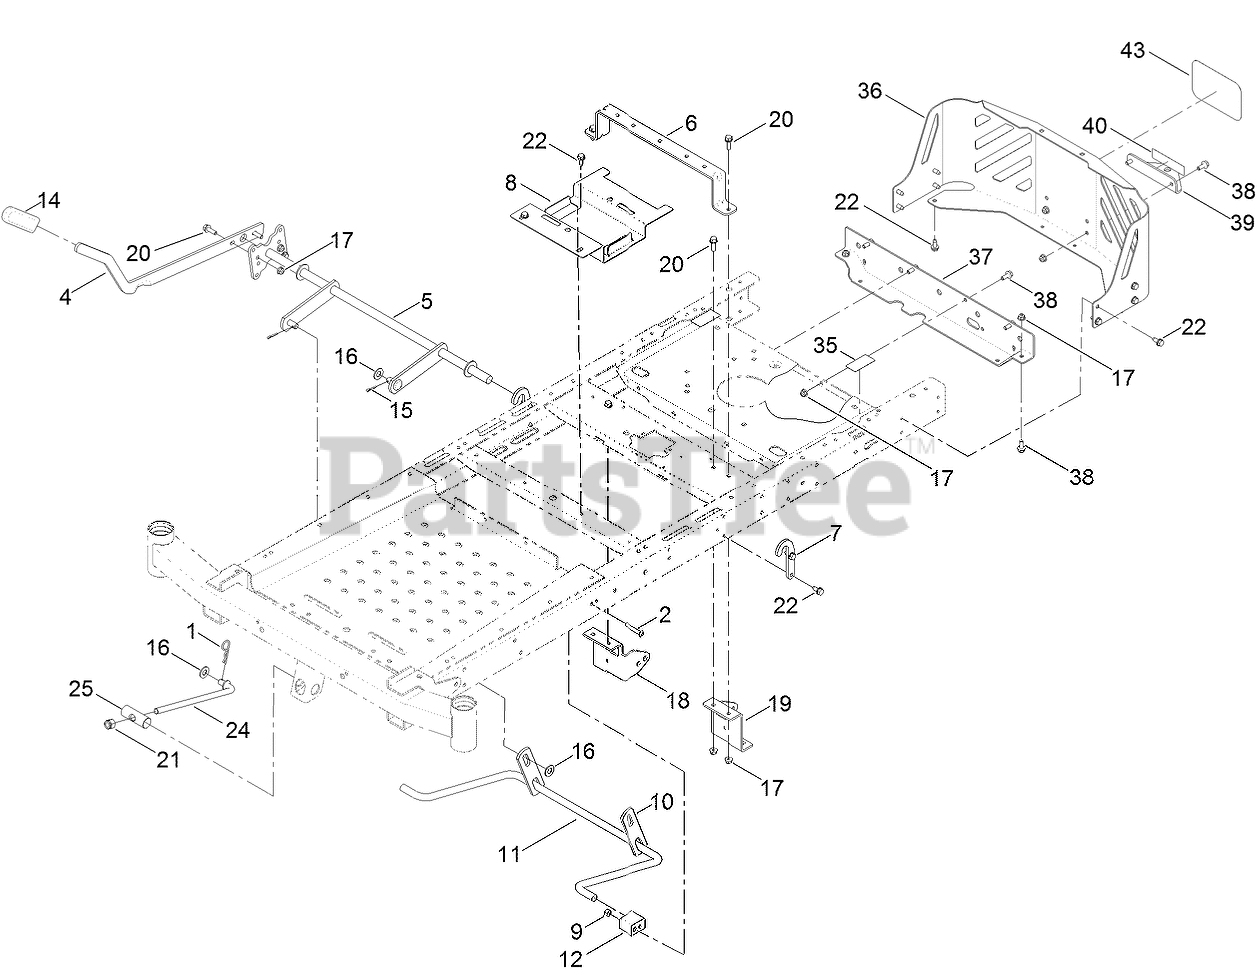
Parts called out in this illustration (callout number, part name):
1	PIN-COTTER
2	SCREW-HSBH
4	LEVER-LIFT
6	BRACE-SEAT, REAR
7	BRACKET-LIFT
8	BRACKET-BATTERY
9	NUT-LOCK, NI
10	LINK-LIFT
11	ARM-LIFT, REAR (WIDE)
12	BLOCK-PIVOT
14	GRIP-LEVER
15	PIN-COTTER
16	WASHER-FLAT
17	NUT-HF, NI
18	MOUNT-HYDRO, FRONT (RH)
19	MOUNT-HYDRO, FRONT (LH)
20	SCREW-HHF
21	NUT-HEX
22	SCREW-HWHTF
24	ROD-MOUNT, DECK
25	PIN-PIVOT
35	DECAL-BYPASS
36	GUARD-ENGINE, WIDE
37	CROSSMEMBER-REAR, WIDE
38	SCREW-HHF
39	BRACKET-HITCH
43	DECAL
